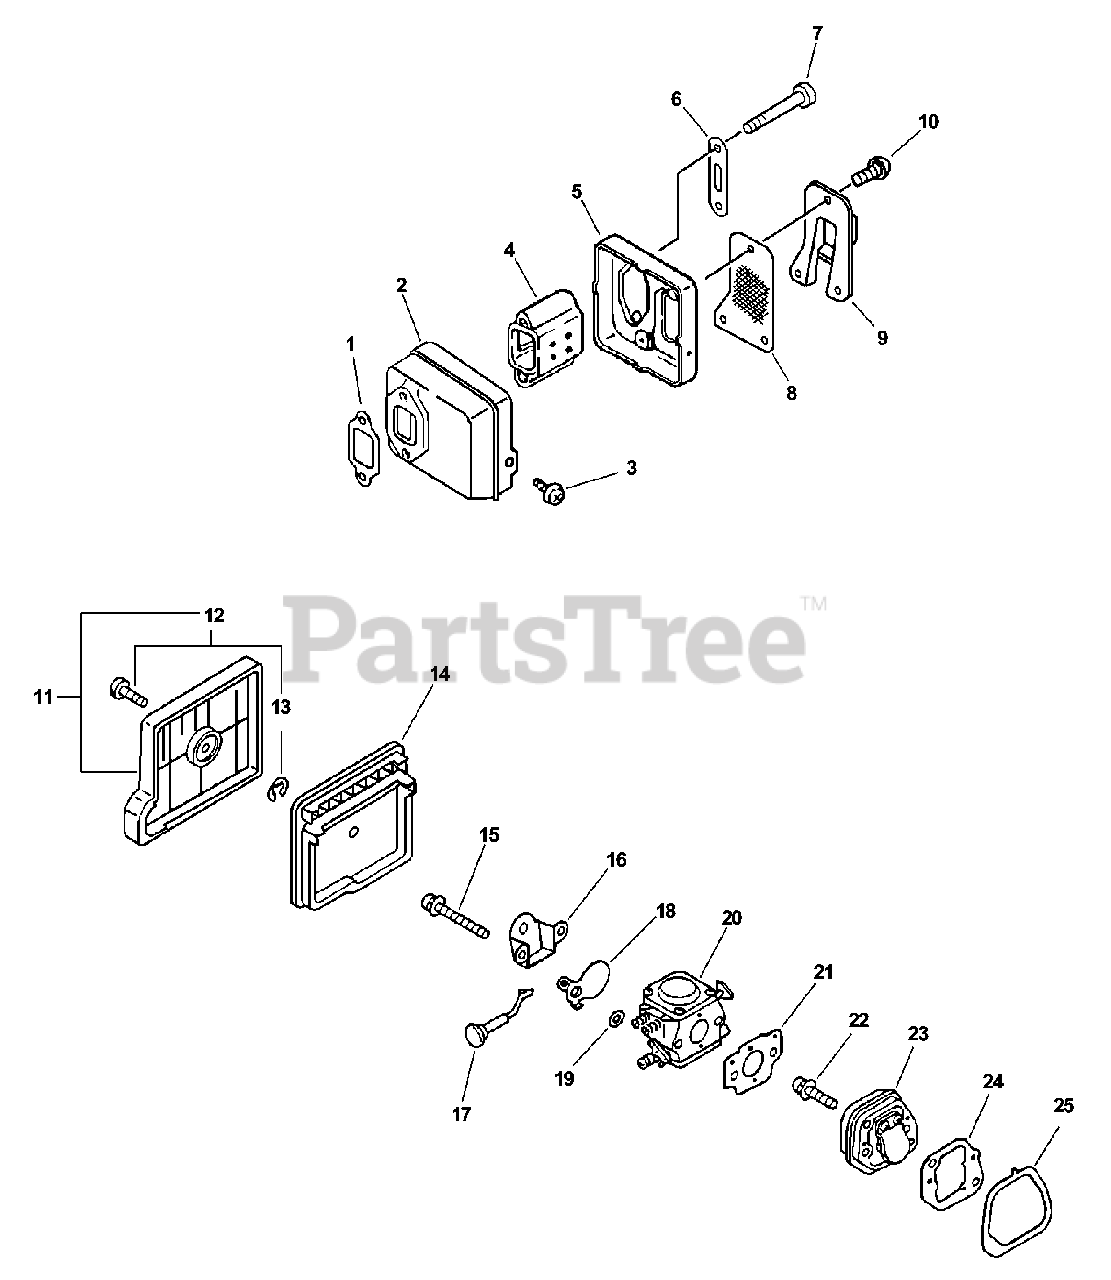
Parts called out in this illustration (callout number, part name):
1	GASKET, EXHAUST
2	GUIDE, EXHAUST
3	SCREW - 4X8
4	BAFFLE, MUFFLER
5	GUIDE, EXHAUST
7	BOLT - FLANGE
8	SCREEN, SPARK ARRESTOR
9	GUIDE, EXHAUST
10	SCREW - 4X8
11	AIR FILTER COVER ASSY
12	THUMBSCREW
13	RING, RETAINING - 4
14	FILTER, AIR
15	SCREW - 5X45
16	PLATE, PREVENT
17	ROD, CHOKE
18	SHUTTER, CHOKE
19	WASHER
20	CARBURETOR WT-589
21	GASKET, INTAKE
22	SCREW - 5X18
23	INSULATOR KIT
24	GASKET, INTAKE
25	SEAL
